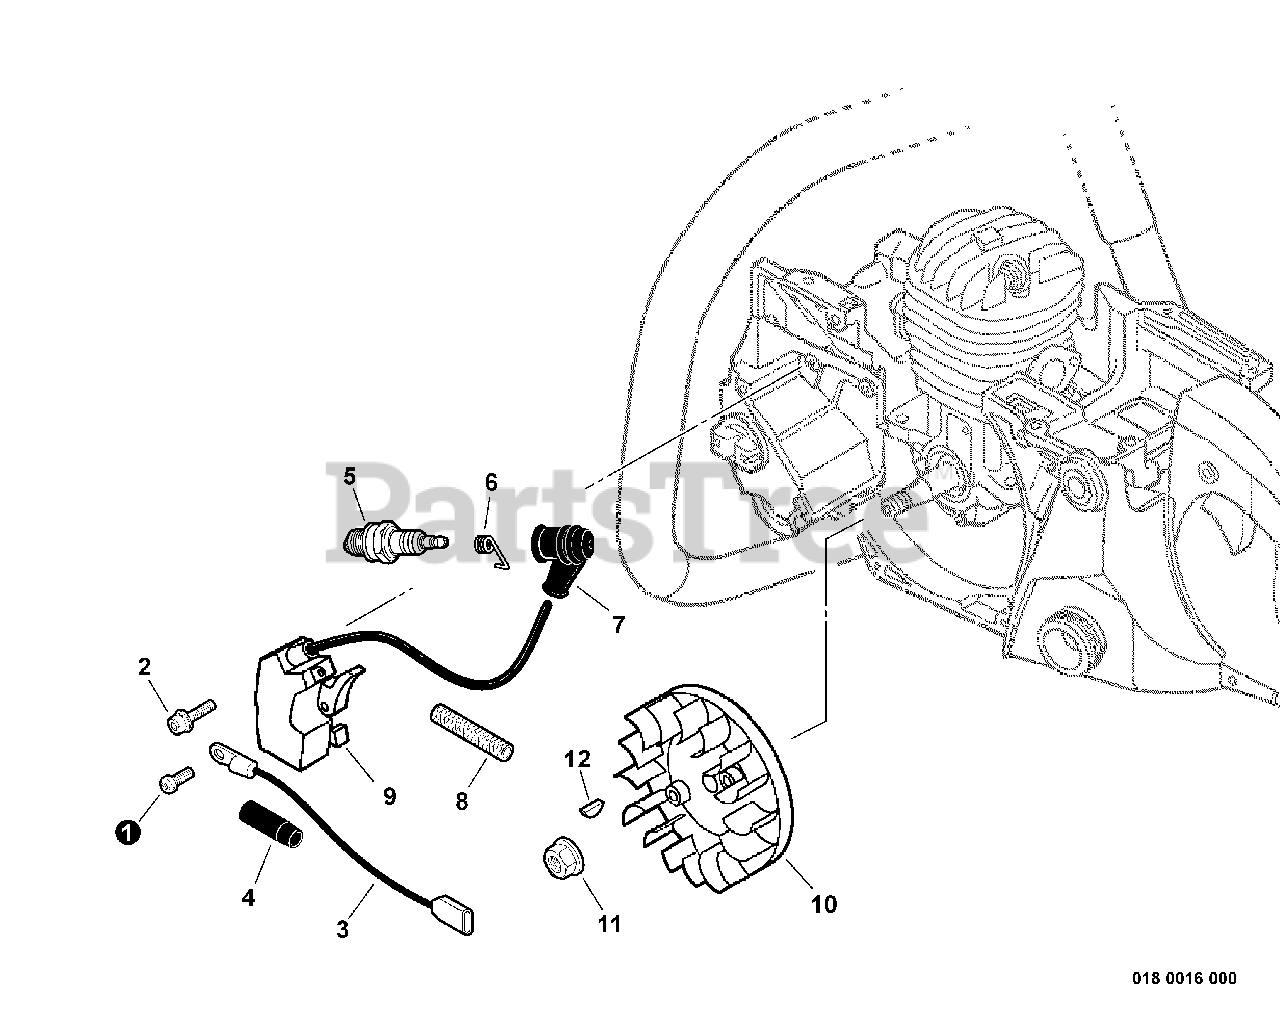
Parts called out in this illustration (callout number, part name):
1	SCREW 4×6
2	BOLT 4×30
3	LEAD #250-210-LA104
4	BOOT, CONNECTOR
5	SPARK PLUG - BPM8Y
5	SPARK PLUG - BPMR8Y
6	TERMINAL, SPARK PLUG
7	CAP, SPARK PLUG
8	TUBE, INSULATOR 7×8.6×40
9	COIL, IGNITION
10	FLYWHEEL
11	NUT, FLANGE M8
12	KEY, WOODRUFF
